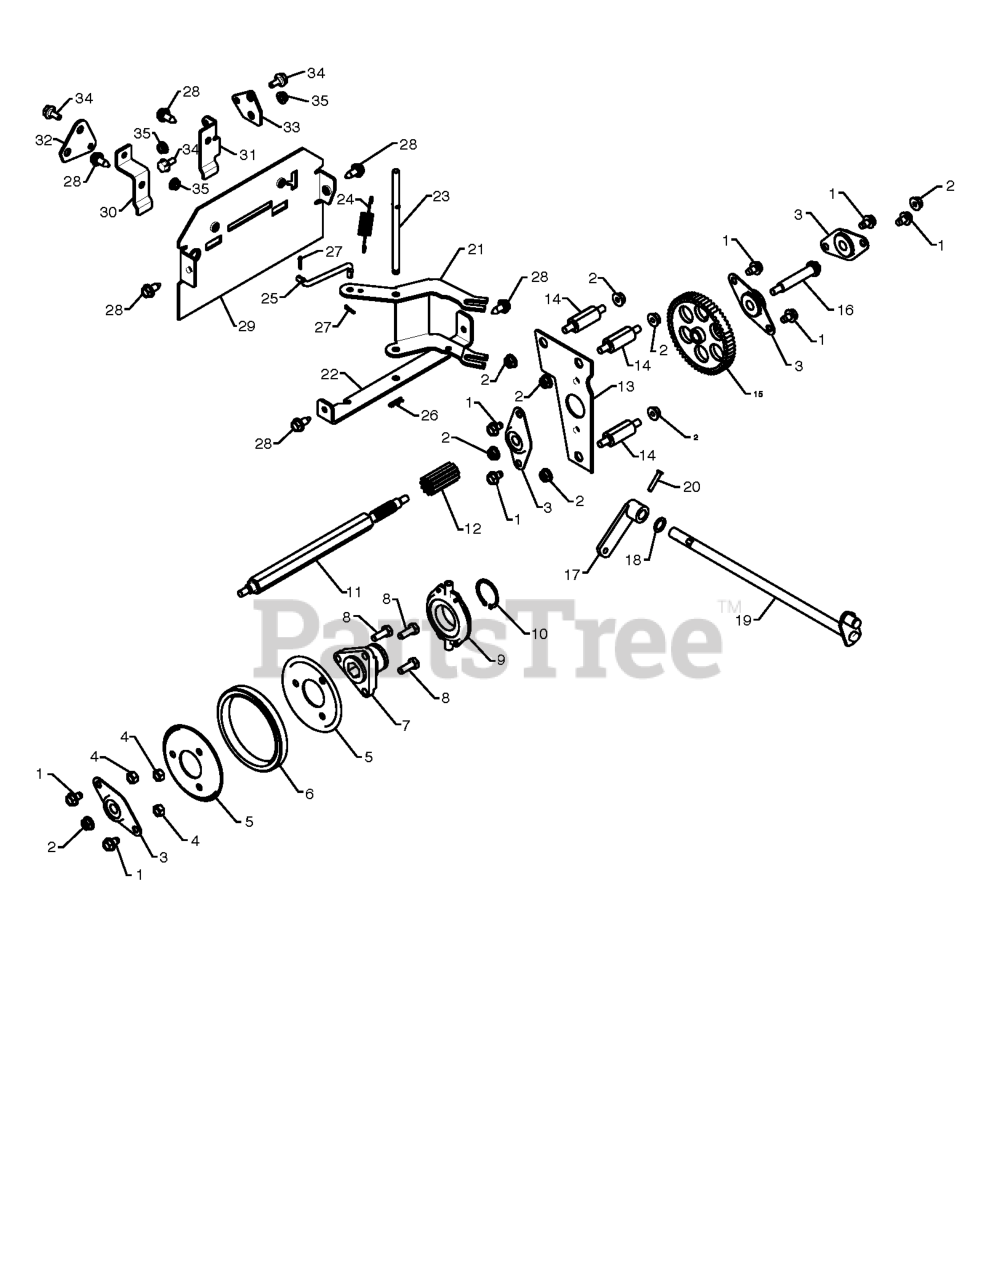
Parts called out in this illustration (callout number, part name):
1	Screw 5/16-18 x 1/2 Hex, Self Tapping 5/16-18 x 1/2
2	NUT.LOCK.5/16-18
3	BEARING, FLANGE
4	NUT.CENTERLOCK.5/16-
5	PLATE.RUBBER.WHEEL
6	RING, RUBBER WHEEL
7	HUB, RUBBER WHEEL
8	BOLT
9	TRUNNION BEARING ASSY
10	RETAINING RING (2 2)(3 2)
11	SHAFT.HEX.LONG
12	GEAR, PINION
13	AUXILLARY PLATE
14	SPACER, PLATE
15	GEAR, INTERMEDIATE
16	SHAFT, AUXILIARY
17	ARM, AUGER CONTROL
18	THRUST WASHER
19	CONTROL.SHAFT.ASM
20	CLEVIS PIN
21	LEVER, SPEED CONTROL
22	BRACKET, PIVOT, SHIFT
23	PIN, PIVOT
24	SPRING, BIAS
25	LINK, SPEED CONTROL
26	RETAINER CLIP PM
27	RETAINER CLIP
28	BOLT.HEX.HD.WASHER.5/16-18X.75
29	PLATE.REAR.SNOW.PNT.ORANGE
30	BRACKET.SHIFTER.PLATE.BZP
31	BRACKET.CLUTCH.PLATE.BZP
32	PLATE.SHIFTER.BZP
33	PLATE.CLUTCH.BZP
34	BOLT.SHOULDER.3/X.25
35	NUT.HEX.FLANGE.1/4
